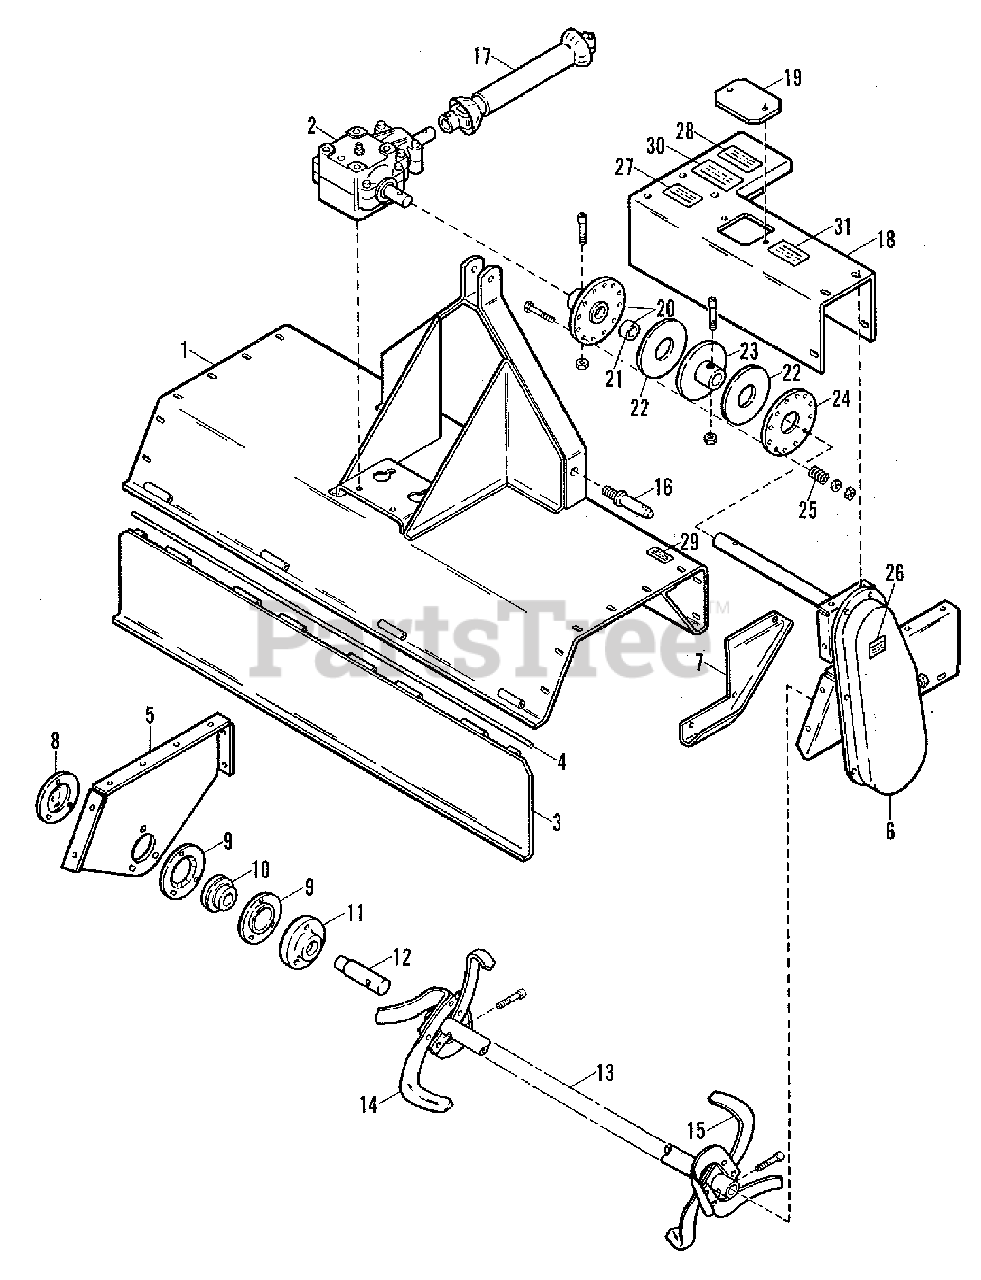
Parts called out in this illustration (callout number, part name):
1	HOUSING, Tiller
2	GEARBOX ASSEMBLY, Complete
2	CAPSCREW, 1/2NC x 1
2	WASHER, Plain, 1/2 x 1 x 14 Ga.
2	LOCKWASHER, 1/2
3	SHIELD, Rear
4	ROD, Rear Shield
4	PIN, Cotter, 1/8 x 1
5	PLATE, End, L.H.
5	CAPSCREW, 3/8NC x 1
5	WASHER, Plain, 3/8 x 3/4 x 16 Ga.
5	LOCKWASHER, 3/8
6	CHAINCASE ASSEMBLY
6	CAPSCREW, 3/8NC x 1
6	WASHER, Plain, 3/8 x 3/4 x 16 Ga.
6	LOCKWASHER, 3/8
7	BOLT, Carriage, 5/16NC x 1-1/4
7	WASHER, Plain, 11/32 x 3/4 x 16 Ga.
7	LOCKWASHER, 5/16
7	NUT, 5/16NC
8	CAPSCREW, 3/8NC x 1-1/2
8	LOCKWASHER, 3/8
9	FLANGE, Bearing
11	COVER, Dust Excluder
12	SHAFT, L.H.
13	TUBE, Tine Mounting
13	CAPSCREW, Socket Head, 1/2NC x 2-1/2, Gr. 8
13	NUT, Lock, 1/2
14	CAPSCREW, 7/16NF x 1-1/2
14	NUT, Crown Lock, 7/16NF
15	CAPSCREW, 7/16NF x 1-1/2
15	NUT, Crown Lock, 7/16NF
16	LOCKWASHER, 7/8
17	UNIVERSAL ASSEMBLY, Complete
17	CAPSCREW, Socket Head, 3/8NC x 2-1/2, Gr. 8
17	NUT, Flange Lock, 3/8NC
18	SHIELD, Clutch
18	CAPSCREW, 5/16NC x 3/4
18	LOCKWASHER, 5/16
18	WASHER, Plain, 11/32 x 3/4 x 16 Ga.
18	CAPSCREW, 1/2NC x 2
18	LOCKWASHER, 1/2
19	COVER, Inspection Hole
19	CAPSCREW, 5/16NC x 3/4
19	LOCKWASHER, 5/16
20	HUB ASSEMBLY
20	CAPSCREW, Socket Head, 1/2NC x 2-1/2, Gr. 8
20	NUT, Lock, 1/2NC
20	CAPSCREW, 3/8NC x 3-1/4
20	WASHER, Plain, 3/8 x 7/8 x 14 Ga.
20	NUT, Lock, 3/8NC
21	BEARING, Bronze
22	DISK, Clutch
23	HUB, Inner Clutch
23	CAPSCREW, Socket Head, 1/2NC x 2-1/2, Gr. 8
23	NUT, Lock, 1/2NC
24	PLATE, Clutch
25	SPRING, Compression
26	DECAL, Caution (Stand Clear)
27	DECAL, Warning (Shield)
28	DECAL, Warning (P.T.O.)
29	DECAL, Warning (Storage Support)
30	DECAL, Notice (Shear Pin)
31	DECAL, Caution (Slip Clutch
